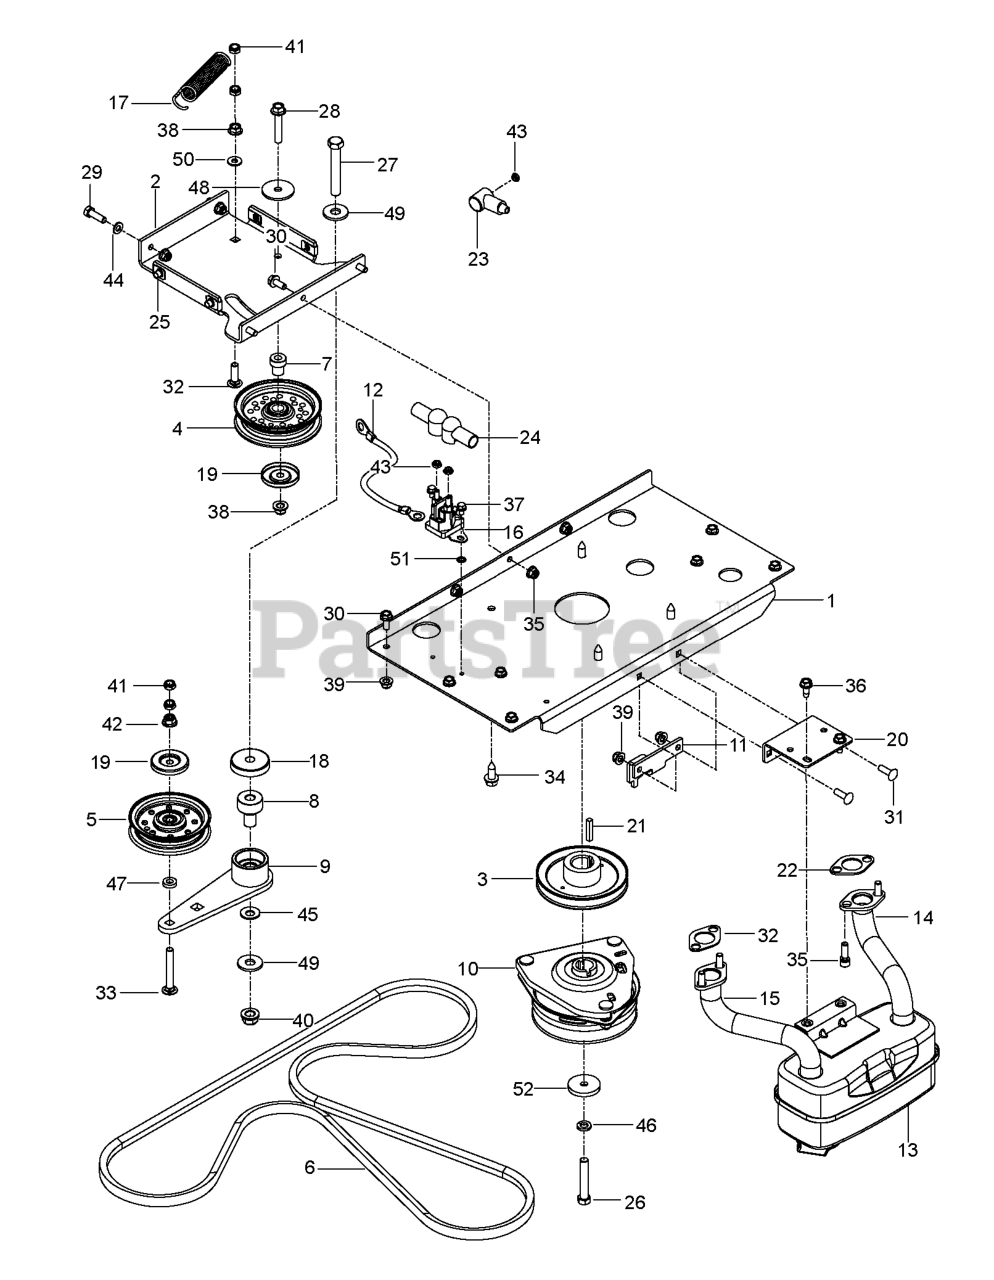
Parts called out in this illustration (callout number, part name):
1	PLATE.PNT.ENGINE.E-DIP
2	PLATE.PNT.IDLER.SUPPORT.E-DIP
3	PULLEY.DRIVE.XMSN
4	IDLER PULLEY
5	PULLEY.IDLER.FLAT.46.PR.DR.
6	BELT, HYDRO, 3400
7	PIVOT, IDLER
8	PIVOT, BEARING
9	ARM, IDLER, STEEL, W/BGS
10	CLUTCH MZ ZTR GT.48/54"1.125"
11	BRACKET.CLUTCH.STOP.PNTX431
12	CABLE POSITIVE
13	MUFFLER ASM TWIN
14	EXHAUST.TUBE.RH.B&S.TWIN.INTEK
15	EXHAUST.TUBE.LH.BS/TWIN
16	SOLENOID.STARTER.BRASS.PLUNGER
17	SPRING, PUMP
18	SHIELD, DUST
19	DUST SHIELD
20	BRKT, MUFFLER, BLK
21	KEY, 1/4 SQ X 1 1/4
22	GASKET.MUFFLER
24	TERMINAL COVER
25	U-CLIP 5/16-18 NUT RETAINER
26	CLUTCH BOLT7/16-20X2.5 GR596HR
27	HCS 1/2C X 3 1/4
28	HHFS 3/8-16 X 2.0 GD 5
29	HCS 5/16C X 1
30	HHFS 5/16-18 X 3/4
31	RHSSNB 5/16C X 1.0
32	RHSNB 3/8-16 X 1-1/4
33	RHSNB 3/8-16 X 2.75
34	SCREW 3/8-16X1
35	SCREW.SOCKET.HEAD.5/16-18
36	SCREW.THDROL.5/16-18X3/4.TTY
37	RP_SCREW.1/4-20X3/8
38	NUT 3/8C WHIZ
39	5/16-18 NYLOC FLANGE NUT
40	NUT, 1/2-13 HEX FLG NYLOC ZD
41	NUT HEX 3/8-16 NYLON, THIN
42	NUT 3/8-16 HEX FLG NYLOC ZD
43	JAM NUT 1/4C (2 2 PW01)
44	WASHER, 3/8 SPEC
45	CONTACT BELLSPR 1/2
46	WASHER 7/16 LOCK
47	WASHER 3/8 X 3/4 X .187 TK
48	WASHER
49	WASH USS FLAT 1/2
50	RP WASHER 3/8 FLAT
51	WASHER 1/4 INT TOOTH
52	SPINDLE WASHER
